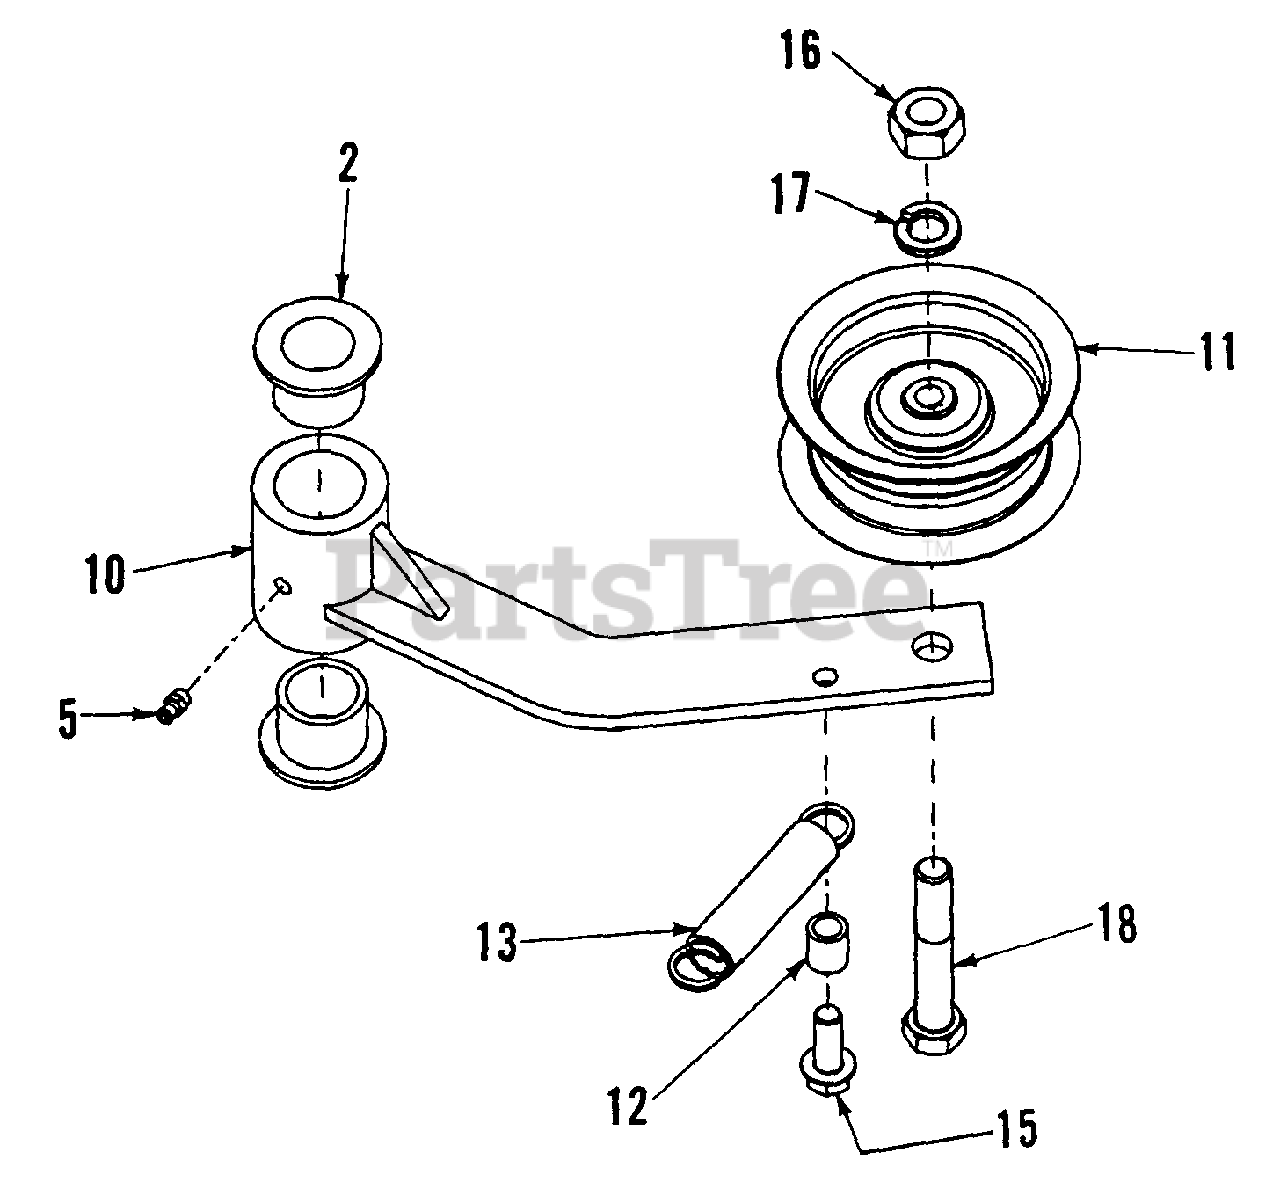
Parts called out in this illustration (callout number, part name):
2	BUSHING, Caster
5	FITTING, Lube 1/4-28 Straight
10	WELDMENT, Idler Arm
11	PULLEY, Flat Idler- 3-1/4" O.D.
13	SPRING, Extension
15	SCREW, 3/8-16 x 1", Hex Washer Self-Tap
16	NUT, 1/2-13 Hex, Grade 5 or B
17	WASHER, 1/2" Split Lock
18	SCREW, 1/2-13 x 3" Hex Head Cap
